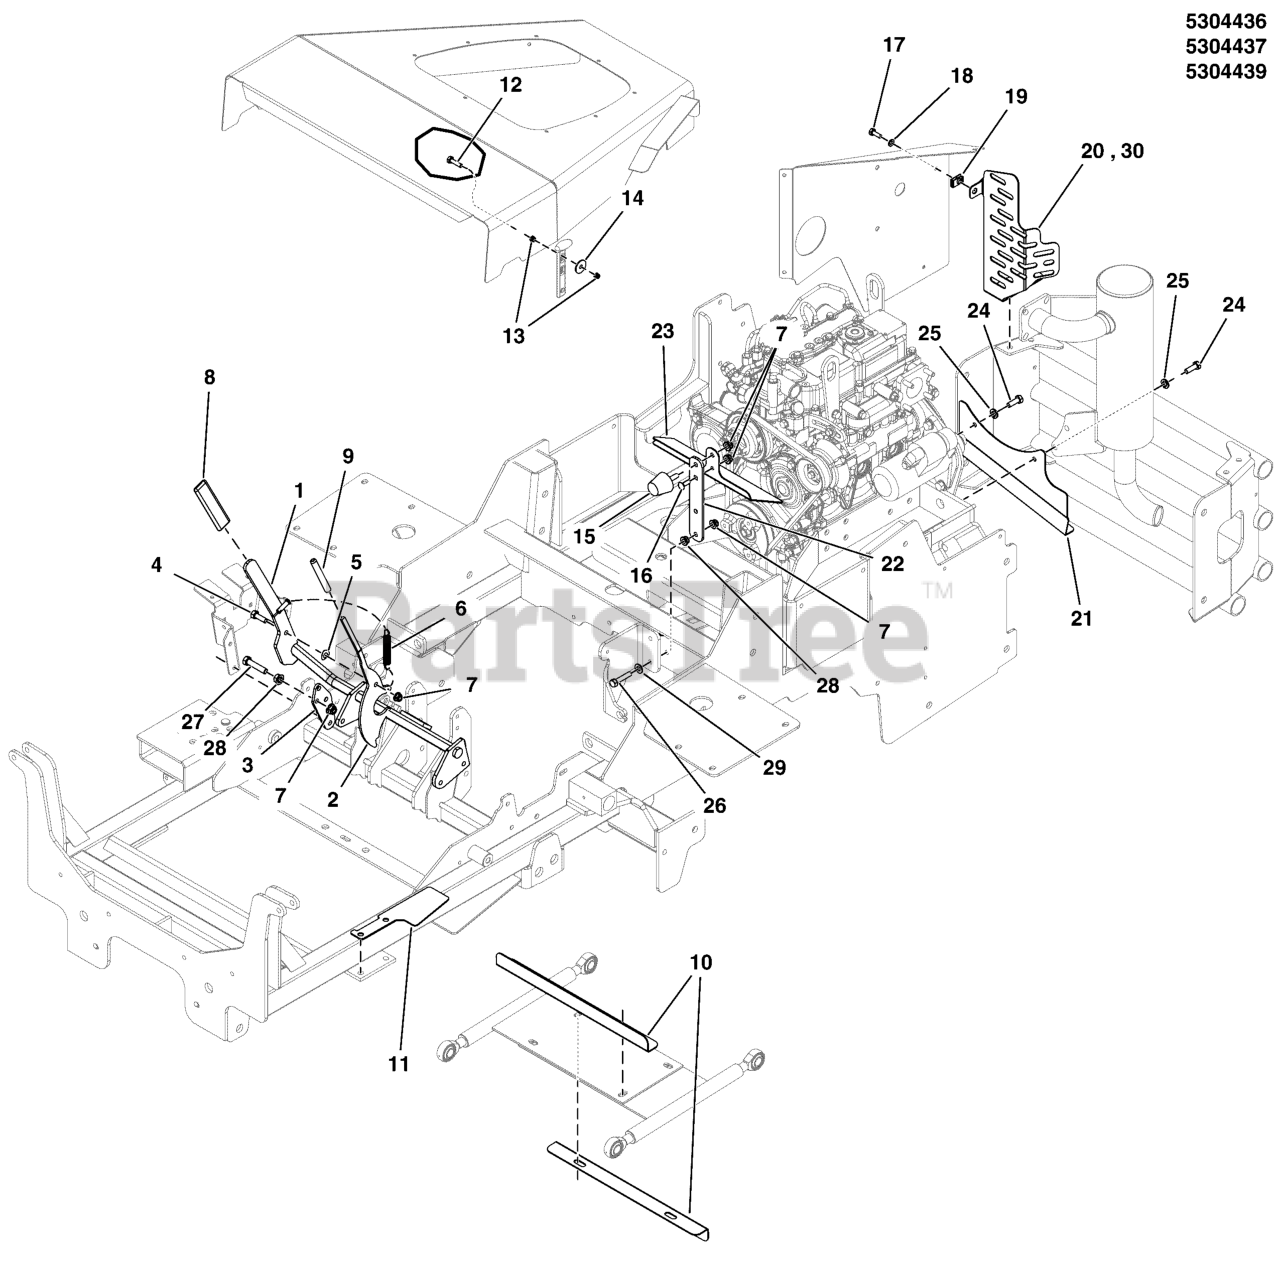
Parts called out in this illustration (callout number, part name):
1	WELD, HANDLE, BRAKE, IS2600 EU - BLK
1	WELD, HANDLE, BRAKE, IS2600 CE - BLK
2	LEVER, BRAKE, IS2600 EU - BLK
3	PLATE, PIVOT MOUNT, BRAKE,IS2600 EU, RED
4	SCREW, TRUSS HD TORX DR5/16-18X0.875 BLK
5	WASHER,WAVE,M10
6	SPRING-EXT, .500 OD X 3.50 LG X .058 WR
7	NUT, 5/16-18 HEX NYLOCK FLANGE NUT
8	GRIP, FOAM, 1/4 X 1 X 4.1
9	COVER, VINYL HANDLE
10	PLATE, GUARD, PULLER BAR,IS2600Z EU, BLK
11	PLATE, DECK SHIELD, FRAME - LH - RED
12	SCREW, 8-32 X 3/4, HEX SERR FLG. GR5, CZ
13	NUT, #8-32 Hex Nylon Lock
14	WASHER, FENDER, #10 X 1-1/4"OD, SS
15	BUMPER, RUBBER 5/16-18
16	BOLT,1/4-20X0.750,GR5,STD NECK,SQ,ZC/CL
17	BOLT, 1/4"-20 X 3/4" GD5 YZ
18	WASHER, 1/4 SAE
19	BODY CLIP, 1/4-20 X 1/2" DEEP
20	PLATE, GUARD, FLY WHEEL, IS2600Z EU, RED
21	PLATE, POWER HEAD BELT GUARD - RED
22	PLATE, BRACKET, SEAT LOCK,IS2600 EU, RED
23	PLATE, REAR SEAT GUARD, IS2600Z CE - RED
24	BOLT, M8-1.25 X 25MM GR 8.8
25	WASHER, 5/16 LOCK CZ
26	BOLT, 5/16-18 X 1-1/2" GD5 YZ
27	BOLT, 5/16-18 X 1-3/4" GD5 YZ
28	NUT, 5/16-18 HEX SERRATED FLANGE (SMALL)
29	WASHER, 5/16" SAE
30	PLATE, GUARD, FLY WHEEL, IS2600Z EU, RED
